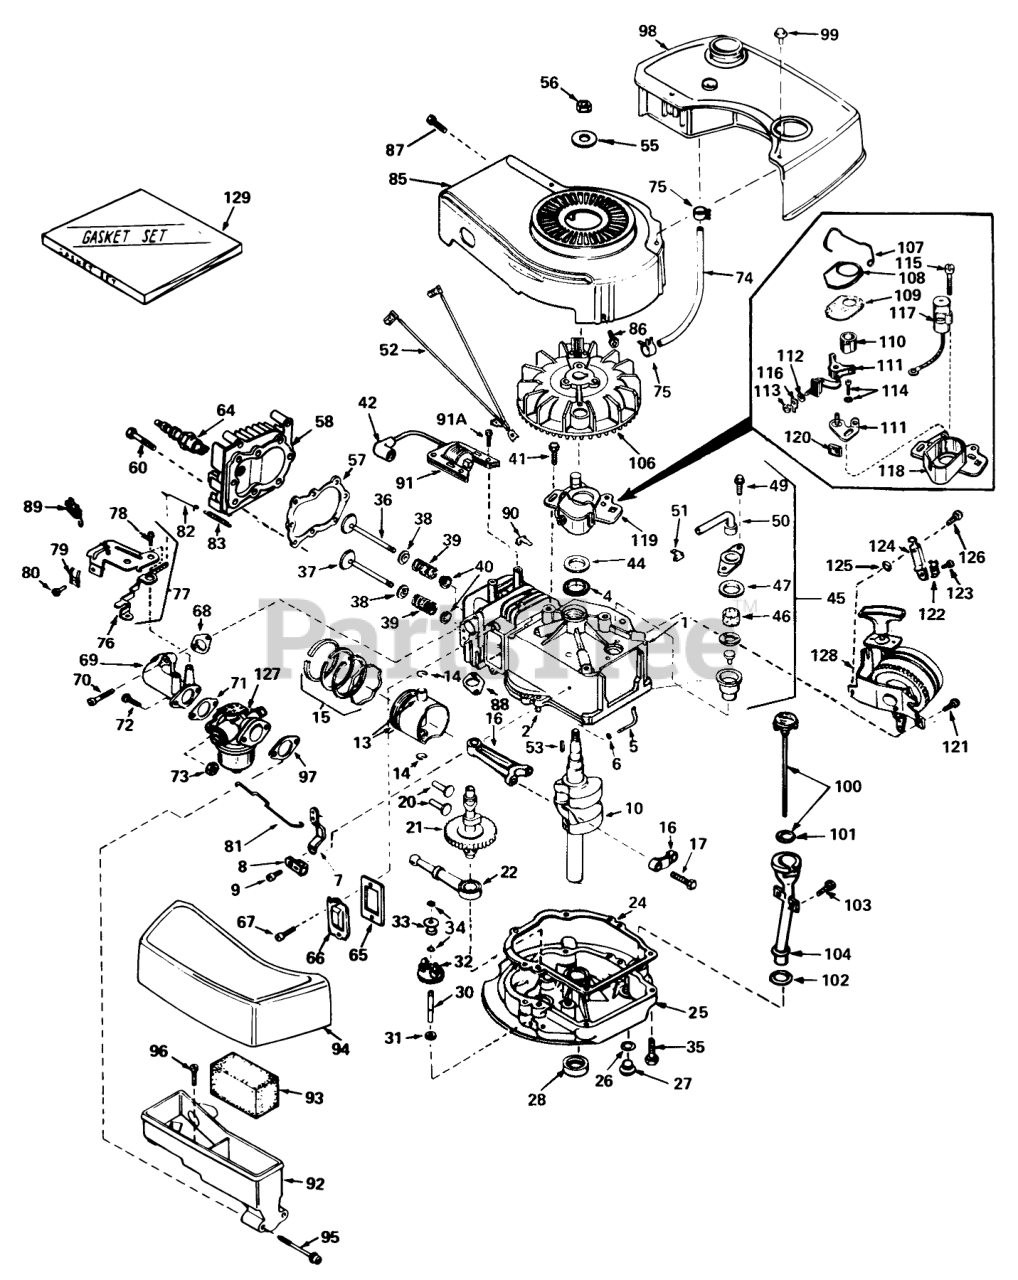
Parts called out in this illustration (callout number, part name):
1	Cylinder Assy. (Incl. #2 & 4)
2	Pin-Dowel
4	Seal-Oil
5	Rod, Governor (Incl. #6)
6	Washer-Flat
7	Governor Lever
8	Clamp-Lever, Governor
9	Screw
10	Crankshaft
13	Piston, Pin & Ring Assy. (Incl. #14 & 15) (Std.)
13	Piston, Pin & Ring Assy. (Incl. #14 & 15) (.OlO oversize)
13	Piston, Pin & Ring Assy. (Incl. #14 & 15) (.020 oversize)
14	Ring-Retaining, Piston Pin
15	Ring Set Piston (Std.)
15	Ring Set Piston (.010 Oversize)
15	Ring Set Piston (.020 Oversize)
16	Rod Assy., Connecting (Incl. #17)
17	Bolt-Rod, Connecting
20	Lifter-Valve
21	Camshaft(Mech.Comp. Release)
22	Oil Pump ASM
24	Gasket, Mounting
25	Flange Assy., Mounting (Incl. #26 thru 30)
26	Gasket-Oil Drain
27	Plug Oil Drain
28	Seal Oil
30	Shaft-Governor
31	Washer-Flat
32	Gear Assy., Governor (Incl. #31)
33	Spool-Governor
34	Ring-Retaining
35	Screw (1/4-20 x 1-1/4)
36	Valve, Intake (Std.) (Incl. #38, 39 & 40)
36	Valve, Intake (1/32" oversize) (Incl. Nos. 38, 39 & 40)
37	Valve, Exhaust (Std.) (Incl. #38, 39 & 40)
37	Valve, Exhaust (1/32" oversize) (Incl. #38, 39 & 40)
38	Cap-Upper Valve Spring
39	Spring-Valve
40	Cap-Valve, Spring
42	Cover-Spark Plug
44	Gasket Stator
45	Breather Assy. (Incl. #46, 47, 49, 50 & 51)
46	Element-Breather
47	Gasket-Breather
49	Screw, Hex Hd. w/Conical
50	Tube, Breaker
51	Clip, Breather
52	Wire Ground
53	682488 LB GRASS HI-
55	Washer-Belleville
56	Nut-Flywheel
57	63573 GIL 42 SNWTHW
58	Head-Cylinder
60	Screw (5/16-18x1-1/2)
64	Plug, Spark (J17LM or equiv.)
64	Plug, Spark (Champion RCJ-8)
65	Gasket-Breather
66	Cover-Valve
68	Gasket, Intake
69	Pipe, Intake
70	Screw (1/4-20 x 1)
71	Gasket-Carburetor
72	Screw (1/4-28 x 7/8)
73	Nut and Lock Washer (1/4-28)
74	Line-Fuel
75	Clamp-Line, Fuel
76	Lever Control
77	Control Assy. Speed (Incl. #76, 78 & 89)
78	Screw, Hex Washer Hd Shoulder Self-Tap
79	Conduit
80	Screw (10-32 x 3/8)
81	Link-Throttle
82	Link Governor Spring
83	Spring Governor
85	Housing Blower
86	Screw
87	Screw (10-24 x 9/16)
88	Gasket Exhaust
89	Terminal
90	Clip-Wire
91	Lamination
91A	Screw
92	Body Air Cleaner
93	Filer, Air
94	Cove, Air Cleaner
95	Screw Fil Hd.
96	Screw, Hex Hd.
97	Gasket-Air Cleaner
98	Tank, Fuel
99	Screw (10-32 x 35/64)
100	Dipstick, Oil (Incl. #101) (Twist Lock)
103	Screw (10-32 x 1/2)
104	Tube-Oil Fill
106	FIywheel
107	Spring Breaker Box
108	Cover-Dust
109	Gasket-Dust Cover
110	Cam-Breaker
111	Breaker Assy.
114	Breaker Screw
115	Condenser Screw
116	Terminal, Ground
117	Condenser
118	Stator Plate
119	Stator Assy. (Incl. #107, 111 thru 118 & 120)
120	Felt,Cam Wiper
121	Screw (1/4-20 x 1/2)
122	Conduit
123	Screw (10-32 x 3/8)
124	Bracker
126	Screw (1/4-20 X 5/8)
127	Carburetor (Incl. #71)
128	Starter
129	53024/VAR.16HP O/P
